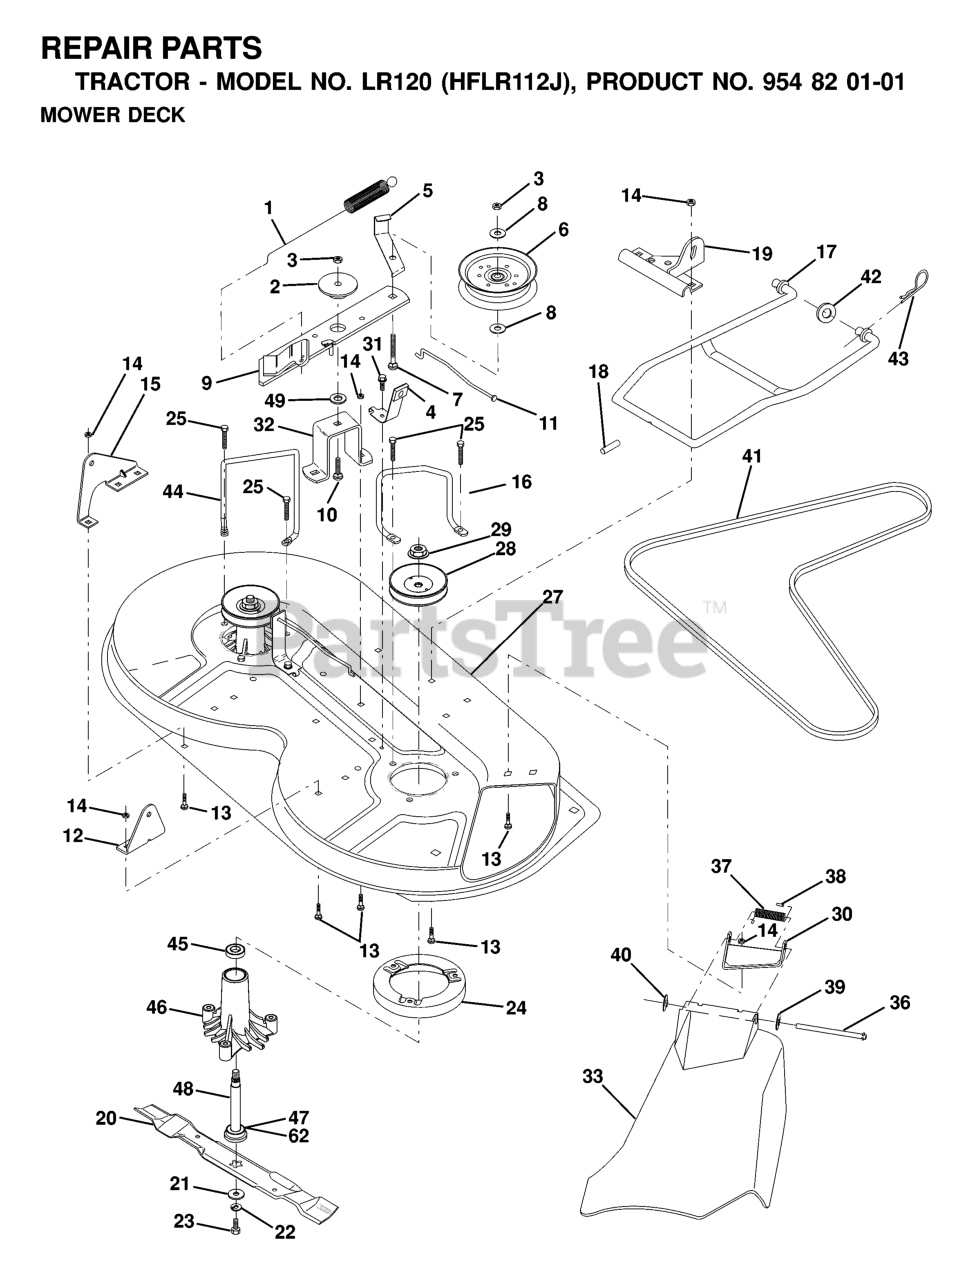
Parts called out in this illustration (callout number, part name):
1	SPRING-MOWER CLUTCH
2	SPACER.RETAINER.MOWER
4	BRAKE ASSEMBLY
5	IDLER BELT GUIDE
6	PULLEY.IDLER.FLAT.MOWER.BLK.PT
8	WASHER
9	IDLER ARM ASSY
10	BOLT.3/8-14X1.25
12	BRKT LIFT REAR
13	RP BOLT 5/16-18 X3/4 ZN/YEL GR
14	LOCKNUT
15	BRKT LIFT REAR LH
16	BELT KEEPER
17	MOWER LINK STABILIZER
18	PIN GROOVE
19	BRKT LINK STABILIIZER
20	BLADE, HI-LIFT 36" PREMIUM
21	WASHER.BLADE
22	LOCKWASHER
23	BLADE BOLT
24	STRIPPER
25	SCREW THDROL ROLLING WASHER HD
27	MOWER HOUSING
28	PULLEY, MANDREL
29	NUT
30	BRACKET ASM DEFLECTOR
31	Screw 5/16-18 x 1/2 Hex, Self Tapping 5/16-18 x 1/2
32	SUPT,IDLER ARM
36	HINGE ROD
37	SPRING TORSION
38	CAP-SLEEVE LT
39	Washer 11/32 x 5/8 x 16 Ga SD
40	NUT PUSH M
41	BELT
42	WASHER
43	SPRING RETAINER
46	HOUSING.MANDREL.VENTED (MACHD)
47	BEARING.BALL.#6204.(MANDREL)
48	SHAFT ASM VENT
49	HARDENED WASHER
62	WASHER FELT
